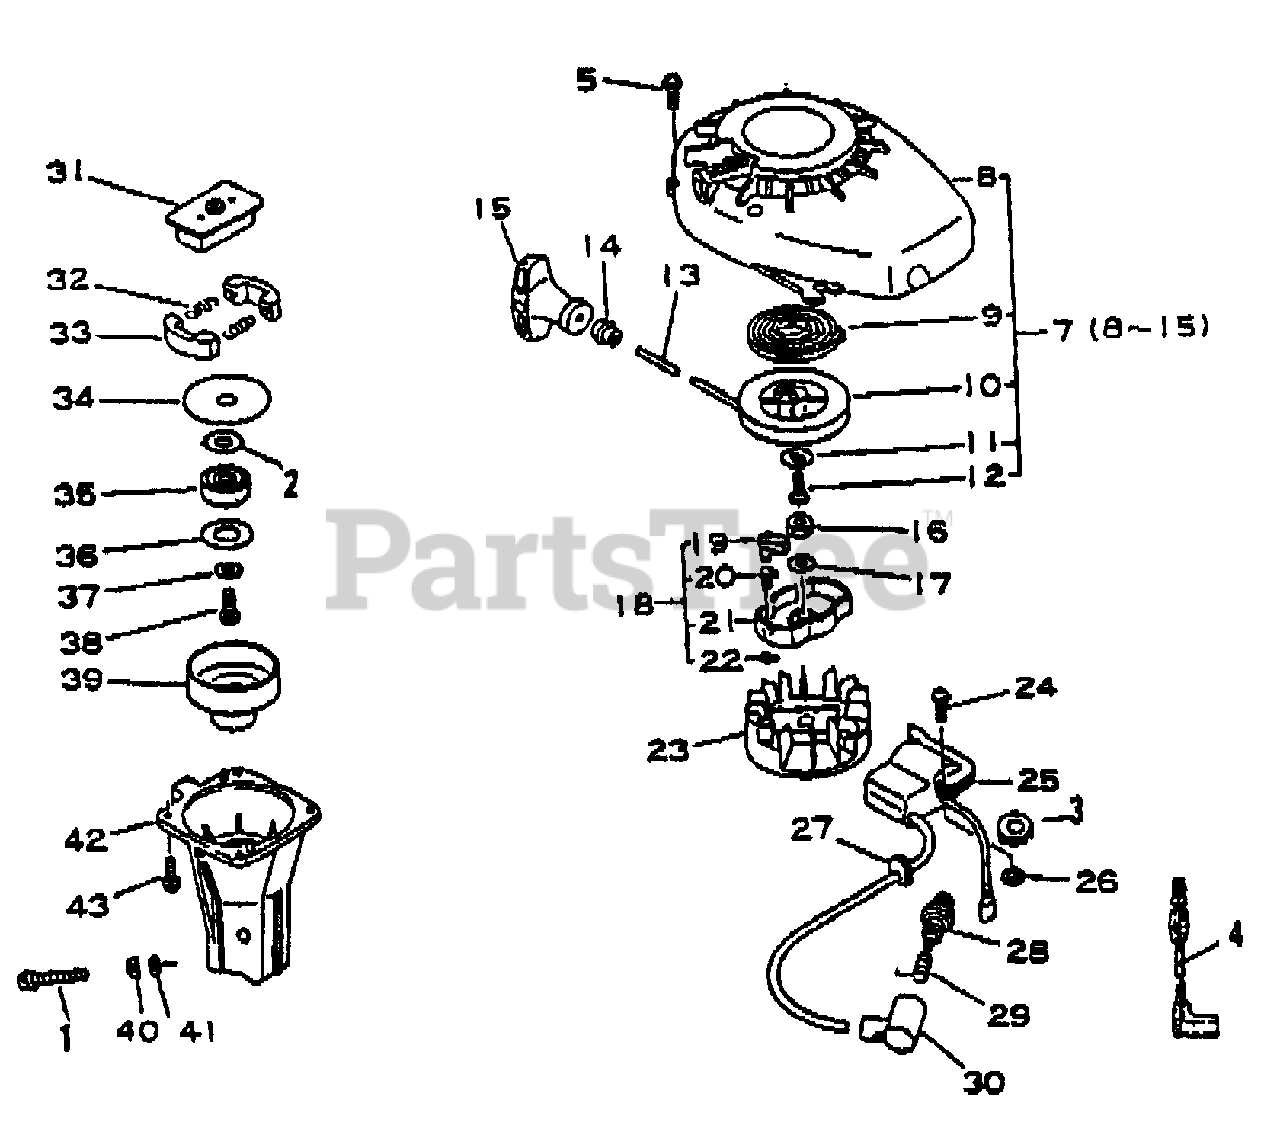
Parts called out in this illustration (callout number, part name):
1	BOLT - 5X25
2	WASHER - 10
4	LEAD
5	SCREW - 4X18
7	STARTER ASSY
8	CASE, STARTER
9	SPRING, REWIND
10	REEL, ROPE
11	WASHER
13	ROPE, STARTER - 3X890
14	GUIDE, ROPE
15	GRIP, STARTER
17	WASHER - 8
18	STARTER PAWL ASSY
19	PAWL, STARTER
20	SPRING, RETURN
21	CATCHER, PAWL
22	RING, RETAINING - 4
23	FLYWHEEL
24	SCREW - 4X22
25	COIL, IGNITION
28	SPARK PLUG -- BPM-6A
29	TERMINAL, SPARK PLUG CAP
30	CAP, SPARK PLUG
31	HUB, CLUTCH
32	SPRING, CLUTCH
33	SHOE, CLUTCH
34	PLATE, CLUTCH
35	BEARING, BALL - 6000
36	WASHER, CLUTCH
37	WASHER - 6
38	SCREW - 6X12
39	DRUM, CLUTCH
40	LOCKWASHER - 5
41	WASHER - 5
42	CASE, CLUTCH
43	SCREW - 4X14
